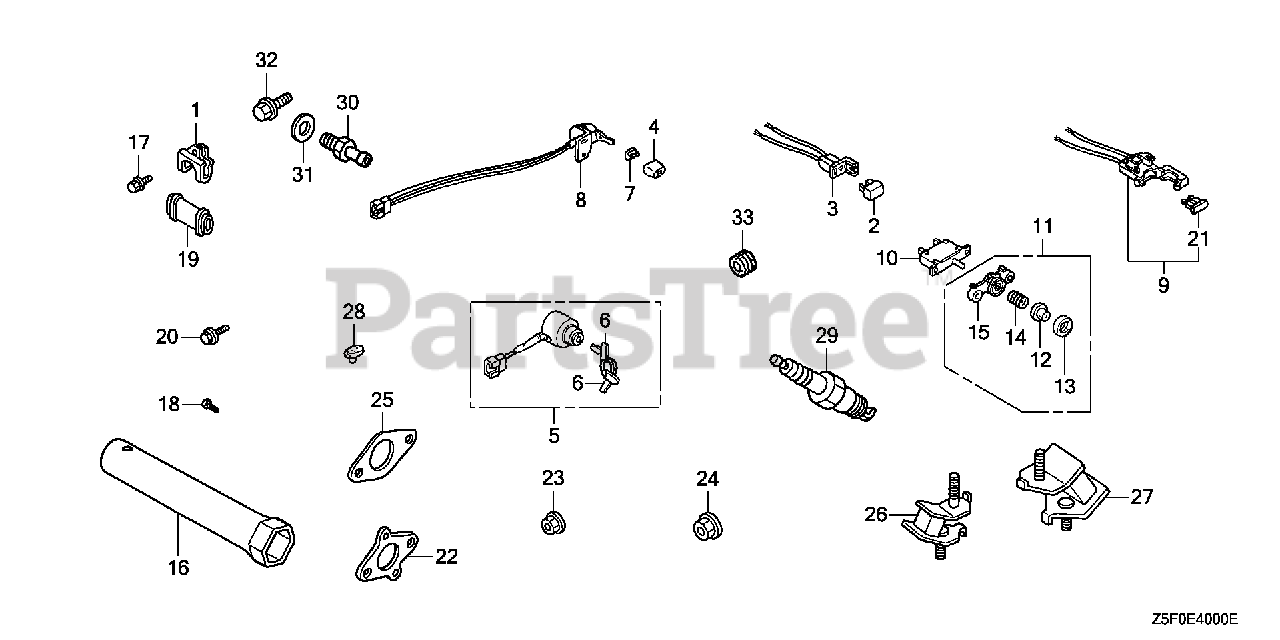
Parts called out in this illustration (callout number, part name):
1	CLIP, WIRE
4	KNOB, PETCOCK LEVER
7	BUSH, CONTROL KNOB
8	SWITCH ASSY., ENGINE STOP
16	WRENCH, PLUG
18	SCREW, GLOVE BOX
